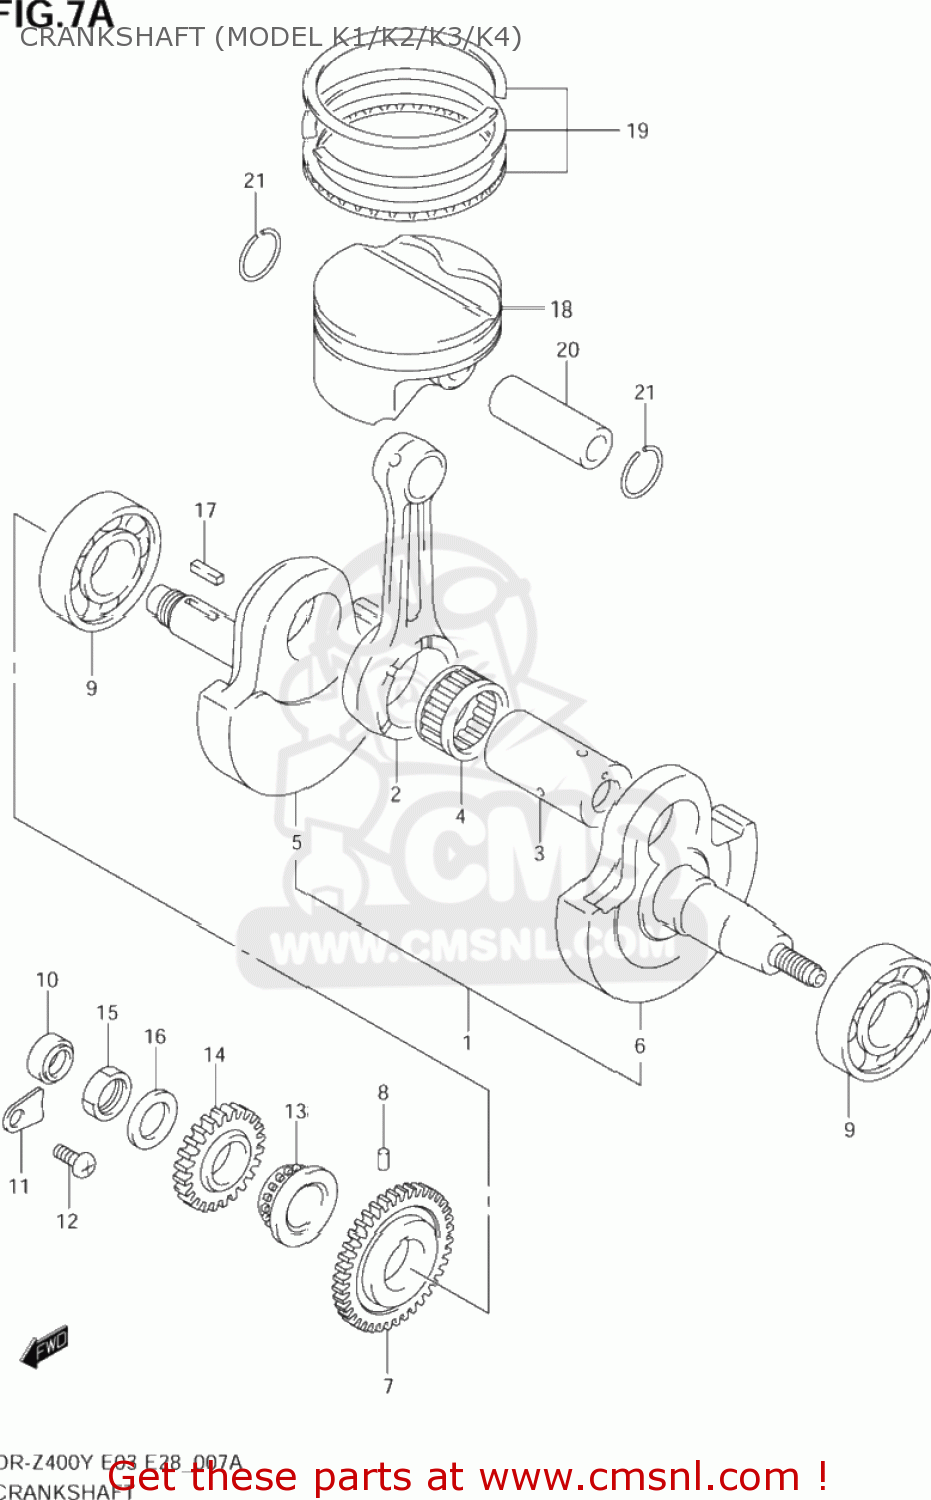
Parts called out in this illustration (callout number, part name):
1	CRANKSHAFT ASSY
2	CONNECTING ROD COMP
3	PIN COMP,CRANK
4	BEARING(35X43X22)
5	CRANKSHAFT, RH
6	CRANKSHAFT,L
7	GEAR,CRANK BALANCER DRIVE
8	PIN(5X8)
9	BEARING(30X72X18)
10	SEAL,OIL(14X24X6)
11	RETAINER,BEARING
12	SCREW
13	SPROCKET,CAM CHAIN DRIVE
14	GEAR,PRIMARY DRIVE
15	NUT
16	WASHER
17	KEY
18	PISTON
19	RING SET,PISTON
20	PIN,PISTON
21	CIRCLIP,PISTON PIN
